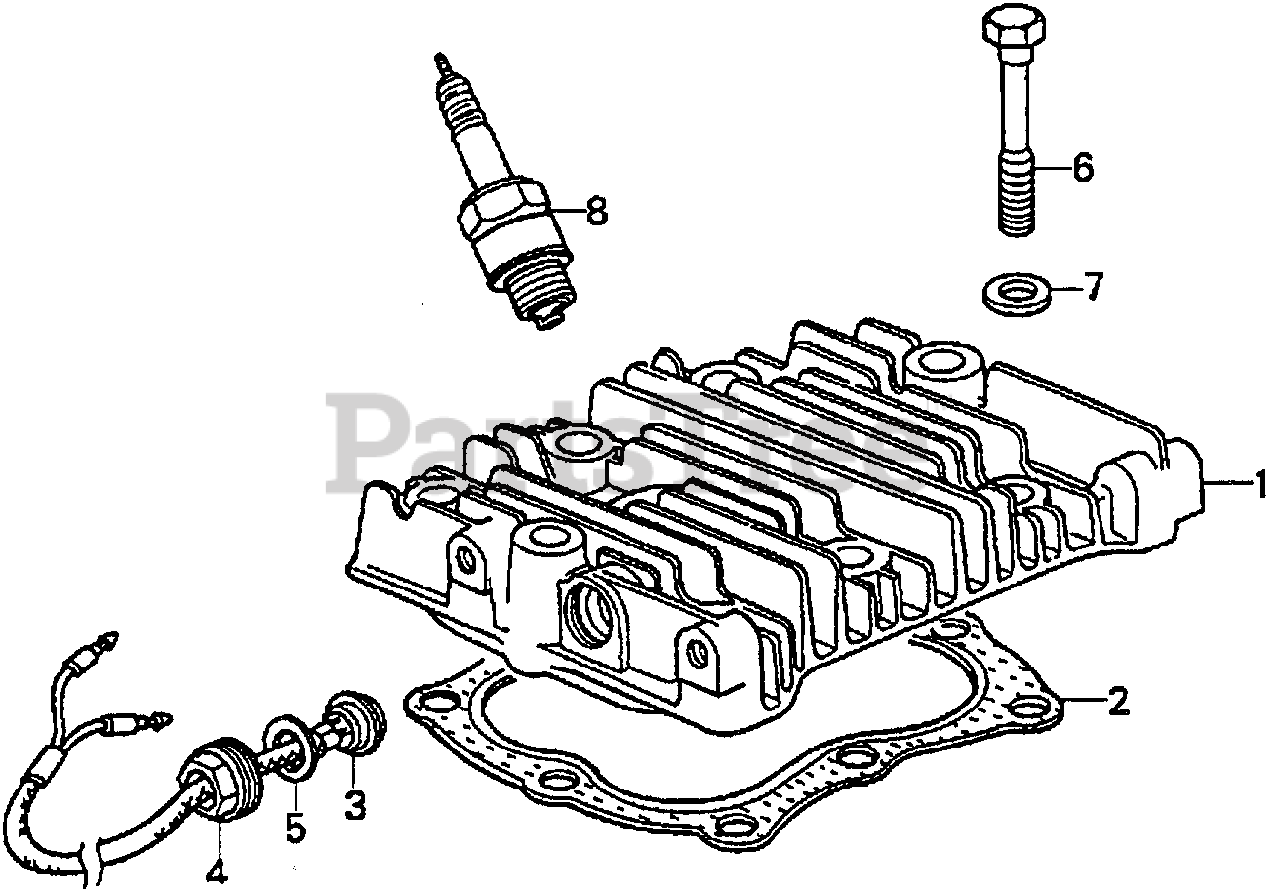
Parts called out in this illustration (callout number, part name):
1	CYLINDER HEAD (NOT AVAILABLE)
2	GASKET, CYLINDER HEAD
3	SWITCH ASSY., THERMOSTAT (NOT AVAILABLE)
4	BOSS, THERMOSTAT SWITCH (NOT AVAILABLE)
5	WASHER, SWITCH BOSS
6	BOLT, HEX. (10X65)
7	WASHER, MAGNET FIXING
8	SPARK PLUG (B6HS) (NGK)
